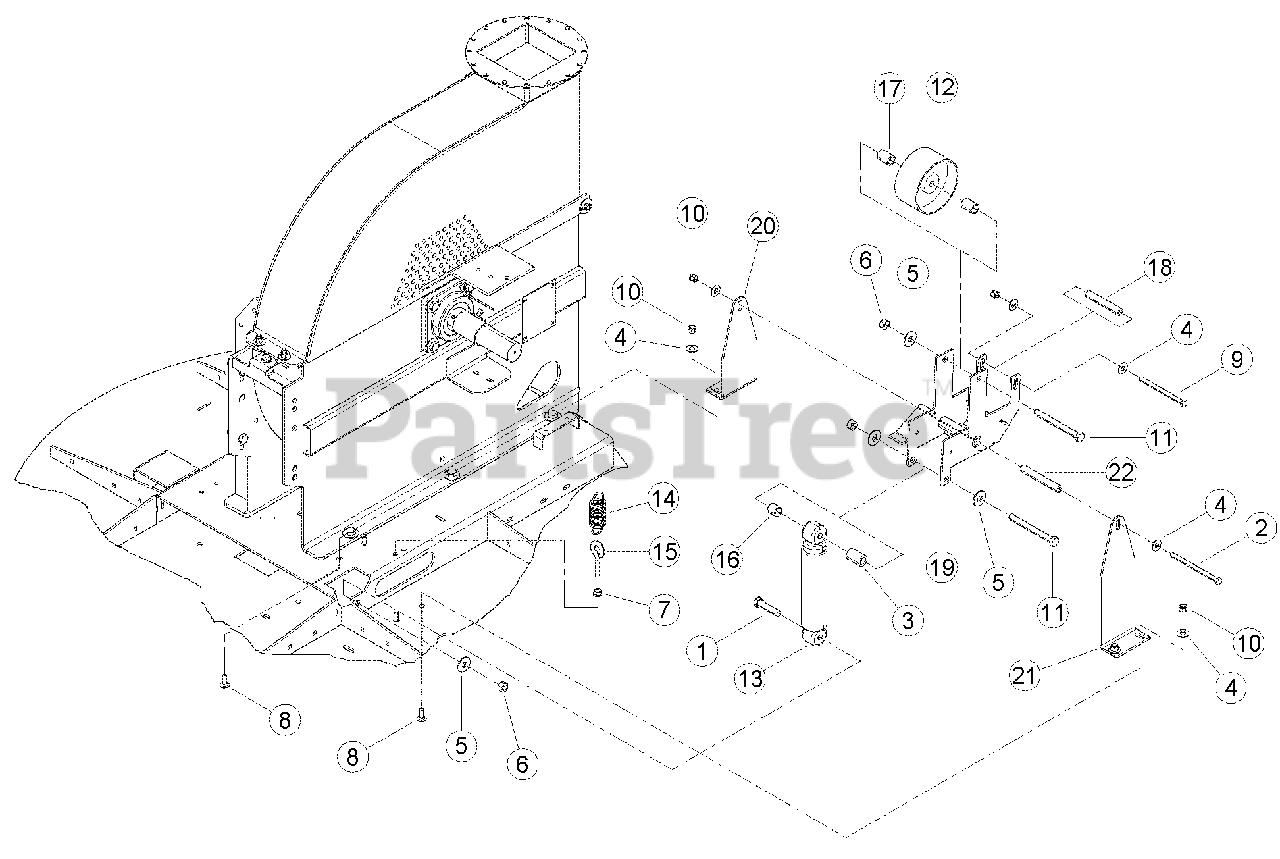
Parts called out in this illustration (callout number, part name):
1	BOLT, 1/2 X 2-1/4 HEX HD GR5 ZP
2	BOLT, 3/8 X 5-1/2 HEX GR5 ZP
3	SPACER, 1.00 X .656 X 1.50 STL
4	WASHER, 3/8 FLAT ZP
5	WASHER, 1/2 FLAT ZP
6	NUT, 1/2 CENTERLOCK GRB ZP
7	NUT, 3/8 SERR FLANGE NC ZP
8	BOLT, 3/8 X 1 CRG GR5 NC ZP
9	BOLT, 3/8 X 5 HEX HD GR5 ZP
10	NUT, 3/8 NE NYLOCK ZP
11	BOLT, 1/2 X 5 HHCS GR5 NC ZP
12	PULLEY, IDLER 5" X 2.50"
13	ABSORBER, IDLER SHOCK
14	SPRING, 1.25OD X 3.50LG X .148WD
15	EYE BOLT, 3/8 X 2 GR2 ZP
16	SPACER, .875 X .81
17	SPACER, .875 X 1.25
18	SPACER, 5/8 OD X 11 GA X 3.80
19	WELDMENT, BELT IDLER
20	ANGLE, IDLER BRACKET
21	ANGLE, IDLER BRACKET
22	SPACER, 5/8 OD X 11 GA X 4.30
